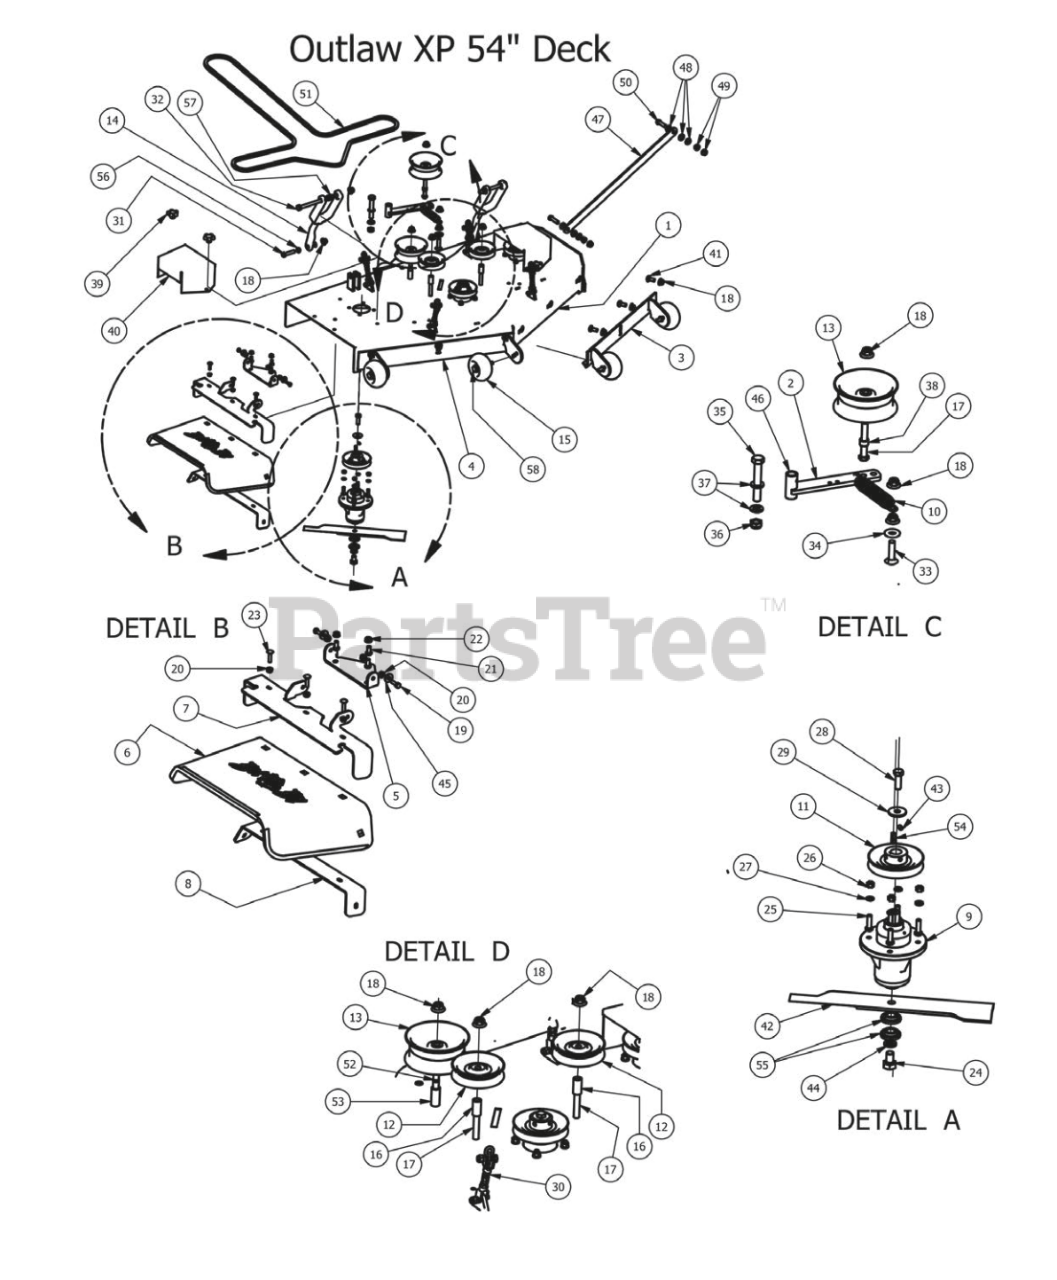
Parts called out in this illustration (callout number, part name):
1	54" Outlaw (Deck Only)
2	Deck Idler Bracket
3	54 Outlaw Adjustable Deck Front (Right)
4	54 Outlaw Adjustable Deck Front (left)
5	Discharge Chute Hanger (deck mounted)
6	Rubber Discharge Chute
7	Dischurge Chu Upper Hanger
8	60" Lower Hanger
9	Double Bearing Spindle Assembly
10	2009 Deck/Pump Idler Spring
11	5" Deck Pulley
12	4 3/4" Idler Pulley
13	5 3/4 Flat Idler-32FI-92-008
14	Deck Hanger
15	Deck Wheel
16	Pulley Spacer
17	1/2 x 3 1/2 Flange Bolt Grade 8
18	1/2-13 Nylon Flange Nut-Orange
19	5/16" x 1" Bolt
20	5/16" Flange Nut
21	3/8" x 3/4" Hex Bolt
22	3/8" Flange Nut
23	5/16" x 1 1/4" Carriage Bolt
24	5/8" x 1 1/2" Grade 8 Bolt
25	3/8" x 1 1/4" Hex Bolt
26	3/8-16 Hex Nuts Zinc
27	3/8" Lock Washer
28	1/2"-20 x 1 1/2 Grade 5 Fine Thread Bolt
29	1/2 Belleville Washer
30	3- Link Adjustable Deck Hange
31	1/2-13X 2-1/4 GR Hex Bolts
32	1/2" x 5 1/2" Bolt
33	1/2 x 2" Carriage Bolt
34	1/2" Flat Washer
35	5/8" x 4" Hex Bolt
36	5/8" Nylock (1/2 Jam)
37	.635 ID Plastic Washer
38	Spacer 3/4 OD X 1/2 ID x .75
39	5/16" Knob
40	Pulley Cover
41	1/2" x 1 1/4 Carriage Bolt
42	54" Deck Fusion Blade For Outlaw
43	3/8" Set Screw
44	5/8" Lock Washer
45	.360 ID Plastic Washer
46	Deck Idler Assembly Componets13,18,17,38,2
47	Panhard Linkage Bar
48	.505 Nylon Spacer
49	1/2" Flange Nut
50	1/2-13x2 GR 5 Hex Bolt
51	B165 Belt-60 54" deck Outlaw
52	1/2" x 4" Bolt (Grade 8)
53	1 3/4" Pulley Spacer
54	1/4" x 1" Key
